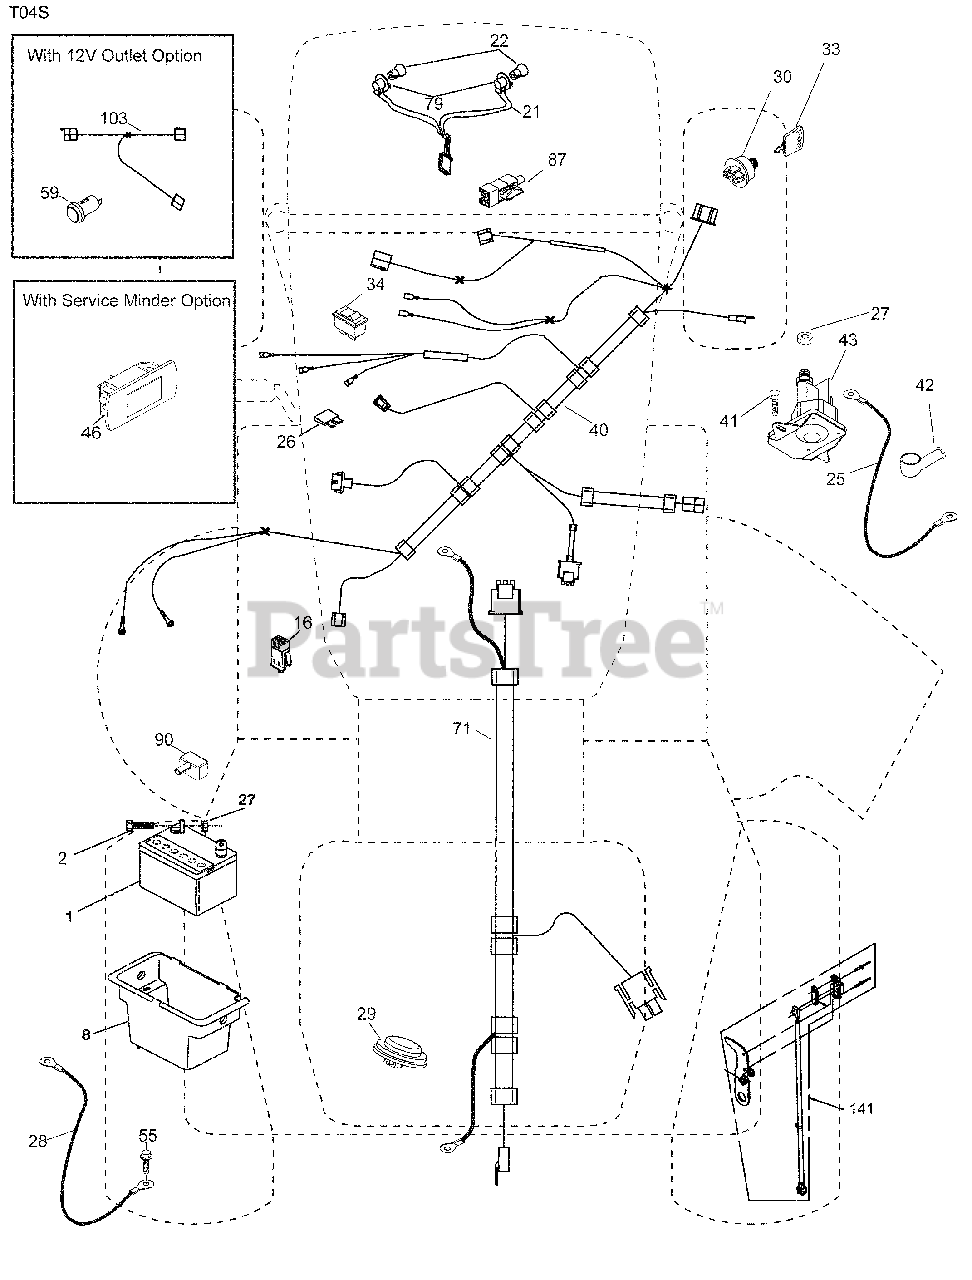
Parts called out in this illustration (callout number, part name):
1	Battery
2	Bolt Hex Head 1/4-20 x 3/4
8	Box Battery
16	Switch Interlock Push-In
21	Harness Socket Light w/4152J
22	Bulb Light
25	Cable Starter
27	Nut Keps Hex 1/4-20 unc
28	Cable, Ground
29	Switch, Seat
30	Switch, Ign
34	Switch Light/Reset
40	Harness Ign. Dash
41	Screw Thd Cut 1/4-20 x 1/2
42	Cover, Terminal
43	Solenoid
46	Gauge Serviceminder Hrmtr
55	Screw Thdrol 5/16-18 x 3/4 TYTT
71	Harness Ign.
79	Socket Asm. Bulb
87	Switch Interlock Clutch
90	Cover Terminal
141	Kit T2 ROS (71677)
